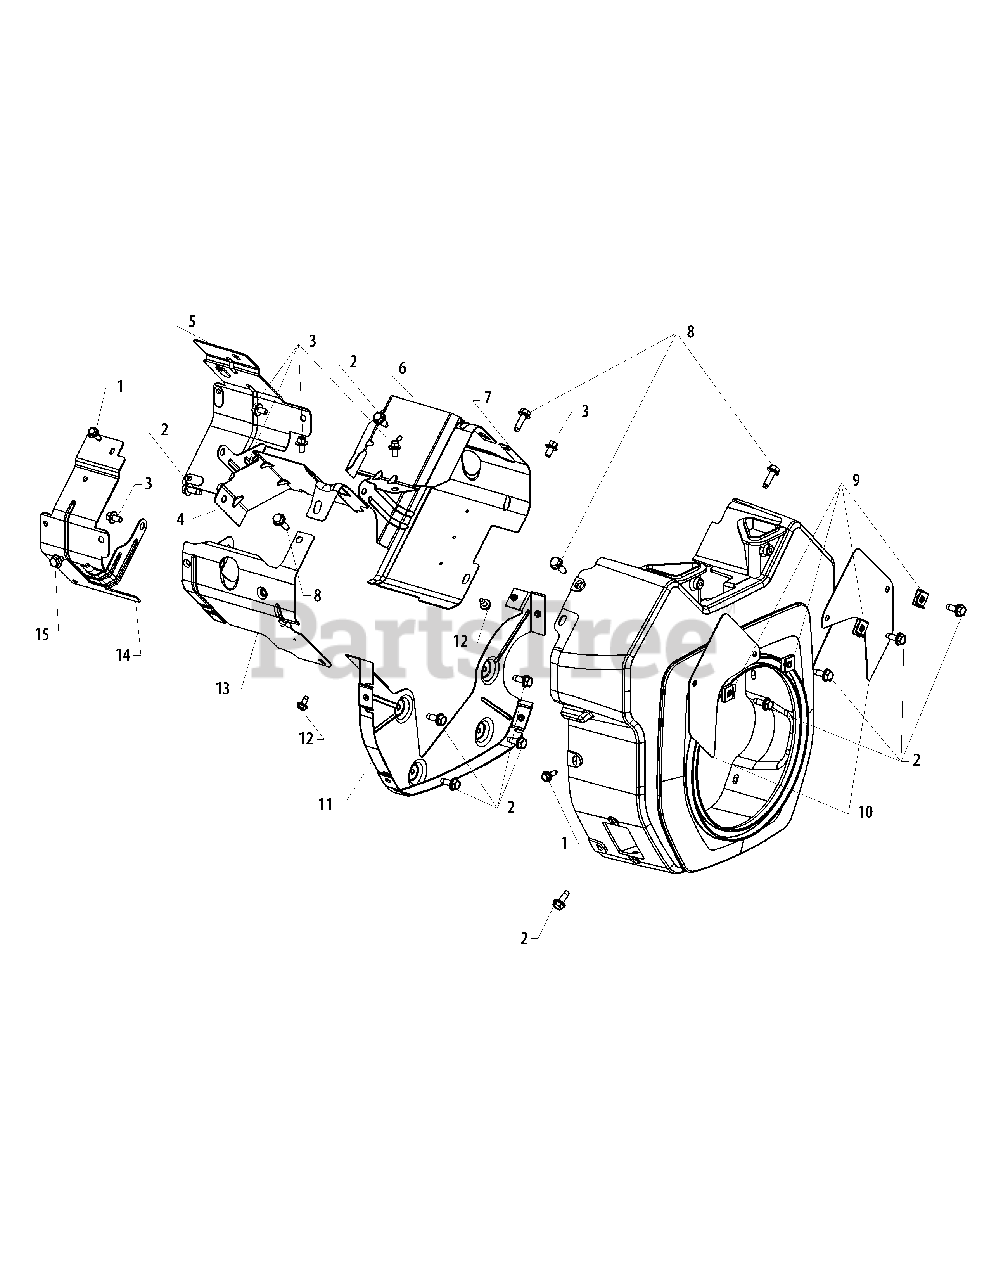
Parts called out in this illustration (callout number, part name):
1	Screw, Flg Thd Frm M5x0.8x16
2	Screw, Flg Thd Frm M6x1.0x16
3	Screw, Flg M6x1.0x10
4	Baffle, Valley #2 Cylinder
5	Baffle, Ducted Air-Starter
6	Baffle, Valley #1 Cylinder
7	Kit, Cyl Barrel - #1 Side
8	Screw, Flg Thd Frm M6x1.0x20
9	Clip, Baffle Mounting
10	Kit, Access Panel
11	Kit, Backing Plate
12	Screw, Flg Thd Frm M5x0.8x10
13	Kit, Cyl Baffle - #2 Side
14	Baffle, Ducted Air-Oil Filter
15	Screw, Flg Thd Frm M6x1.0x10
